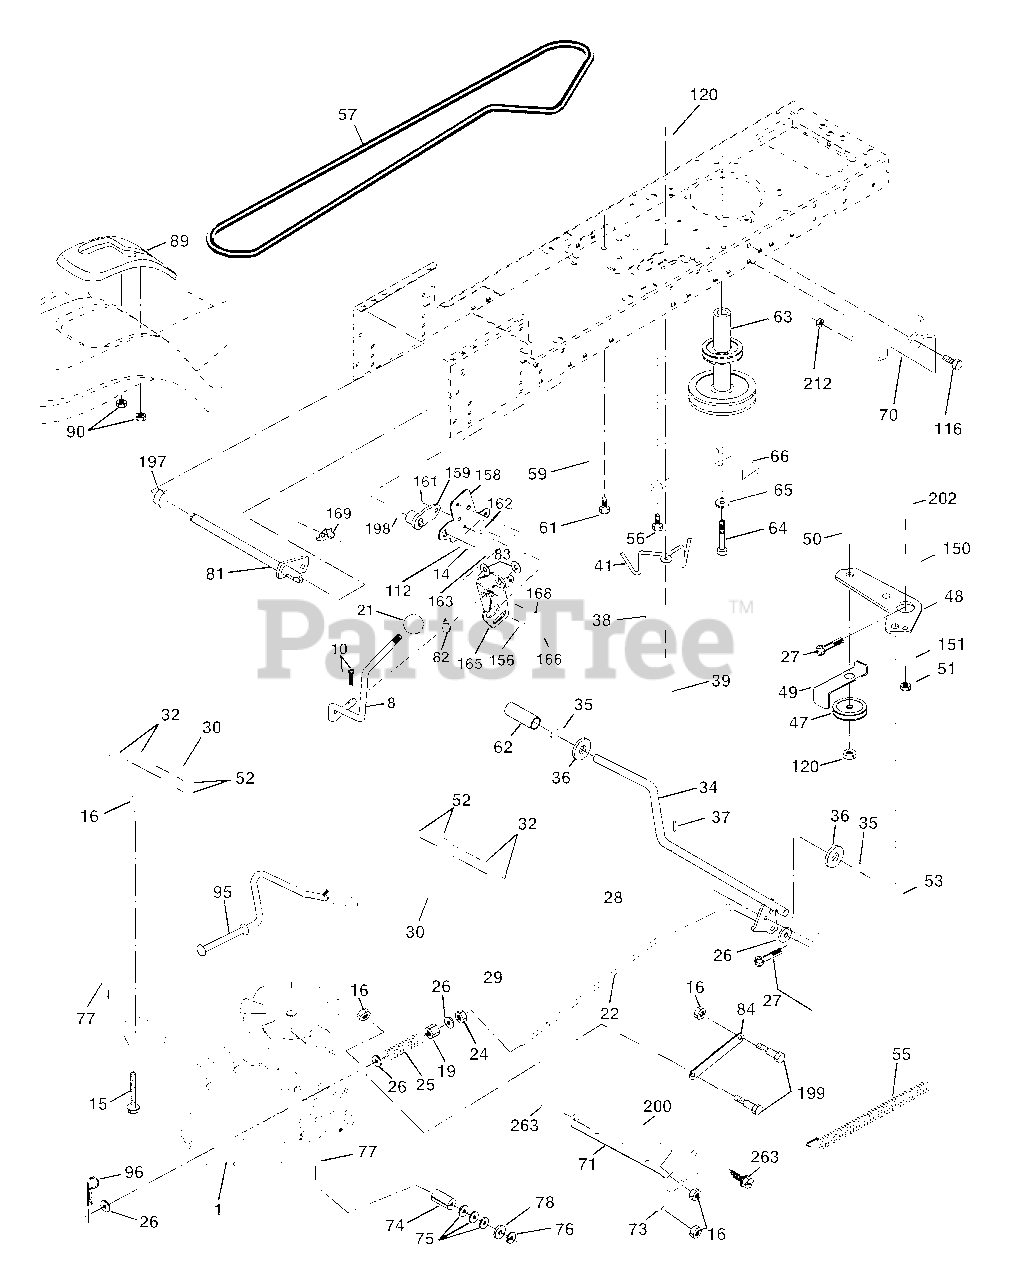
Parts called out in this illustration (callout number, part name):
8	Rod Shift Fender
10	Pin Cotter 1/8 x 1 CAD
14	Washer Lock Hvy Helical 1/4
15	Bolt Hex Flg Hd 5/16-18 x Gr.5
16	Nut Lock Hex W/Ins. 5/16-18 unc
19	Nut Lock Hex W/Wsh 3/8-16 unc
21	Knob, Deluxe
22	Rod, Brake Hydro
24	Nut
25	Spring, Brake Rod
26	Washer
27	Pin Cotter 1/8 x 3/4 CAD.
28	Rod, Parking Brake
29	Cap, Parking Brake
30	Bracket, Transaxle
32	Bolt Hex Hd 5/16-18 unc x 3/4
34	Shaft, Foot Pedal
35	Bearing, Nylon
37	Pin, Roll
38	Pulley, Composite
41	Keeper, Belt Idler
47	Pulley, Idler, V-Groove
48	Bellcrank Clutch Grnd Drv Stl
49	Retainer, Belt
52	Nut Crownlock 5/16-18
53	Link, Clutch
55	Spring, Return, Clutch
56	Screw 3/8-16 x 1-1/4
57	V-Belt, Ground Drive
59	Keeper, Center Span
61	Screw 3/8-16 x .875
62	Cover, Pedal
63	Pulley, Clutch Eng
64	Bolt Hex 7/16-20 x 4 Ga. 5
65	Washer
66	Keeper Belt Engine
70	Guide Belt Mower Drive RH
71	Strap Torque Lh Hydro
73	Strap Torque Rh Hydro
74	Spacer, Axle
75	Washer 25/32 x 1-1/4 x 16 Ga.
77	Key, Square
78	Washer 25/32 x 1-5/8 x 16 Ga.
81	Shaft Asm. Cross Hydro
82	Spring Torsion T/A
83	Washer 17/32 x 3/4 x 16 Ga.
84	Link Transaxle
89	Console, Shift
95	Control Asm Bypass Hydro
96	Retainer Spring 1" Zinc/Cad
112	Washer 9/32 x 3/4 x 10 Ga.
116	Boulon 3/8-16 x 1
120	Nut Lock Flg 3/8-16
150	Spacer Retainer
151	Washer 13/32 x 2 x 10 Ga.
156	Washer Srrtd 5/16 ID x 1.0 x .125 Tk
158	Bracket Shift Mount
159	Hub Shift
161	Bolt Rdhd Sqnk 1/4-20 x 3/4 Gr. 5
162	Nut Crownlock 1/4-20 unc
163	Bolt Hex Fin 1/4-20 unc x 1 Gr. 5
165	Bracket Pivot Lever
166	Screw 5/16-18 x 5/8 TT Yellow
168	Bolt Shoulder 5/16-18 x .561 TT
169	Plate Fastening Cross Shf. STLT/CRD
197	Nyliner Snap-In 5/8" ID
198	Washer Nyl. 7/8 ID x .105"
199	Bolt Shoulder 5/16-18 unc
200	Bolt Rdhd Sq Neck 5/16-18 unc x 1
202	Bolt Carr Sh 3/8-16 x 1-3/4 Gr. 5
212	Nut Hex Flg Lock
263	Screw 3/8-16 x 3/4
